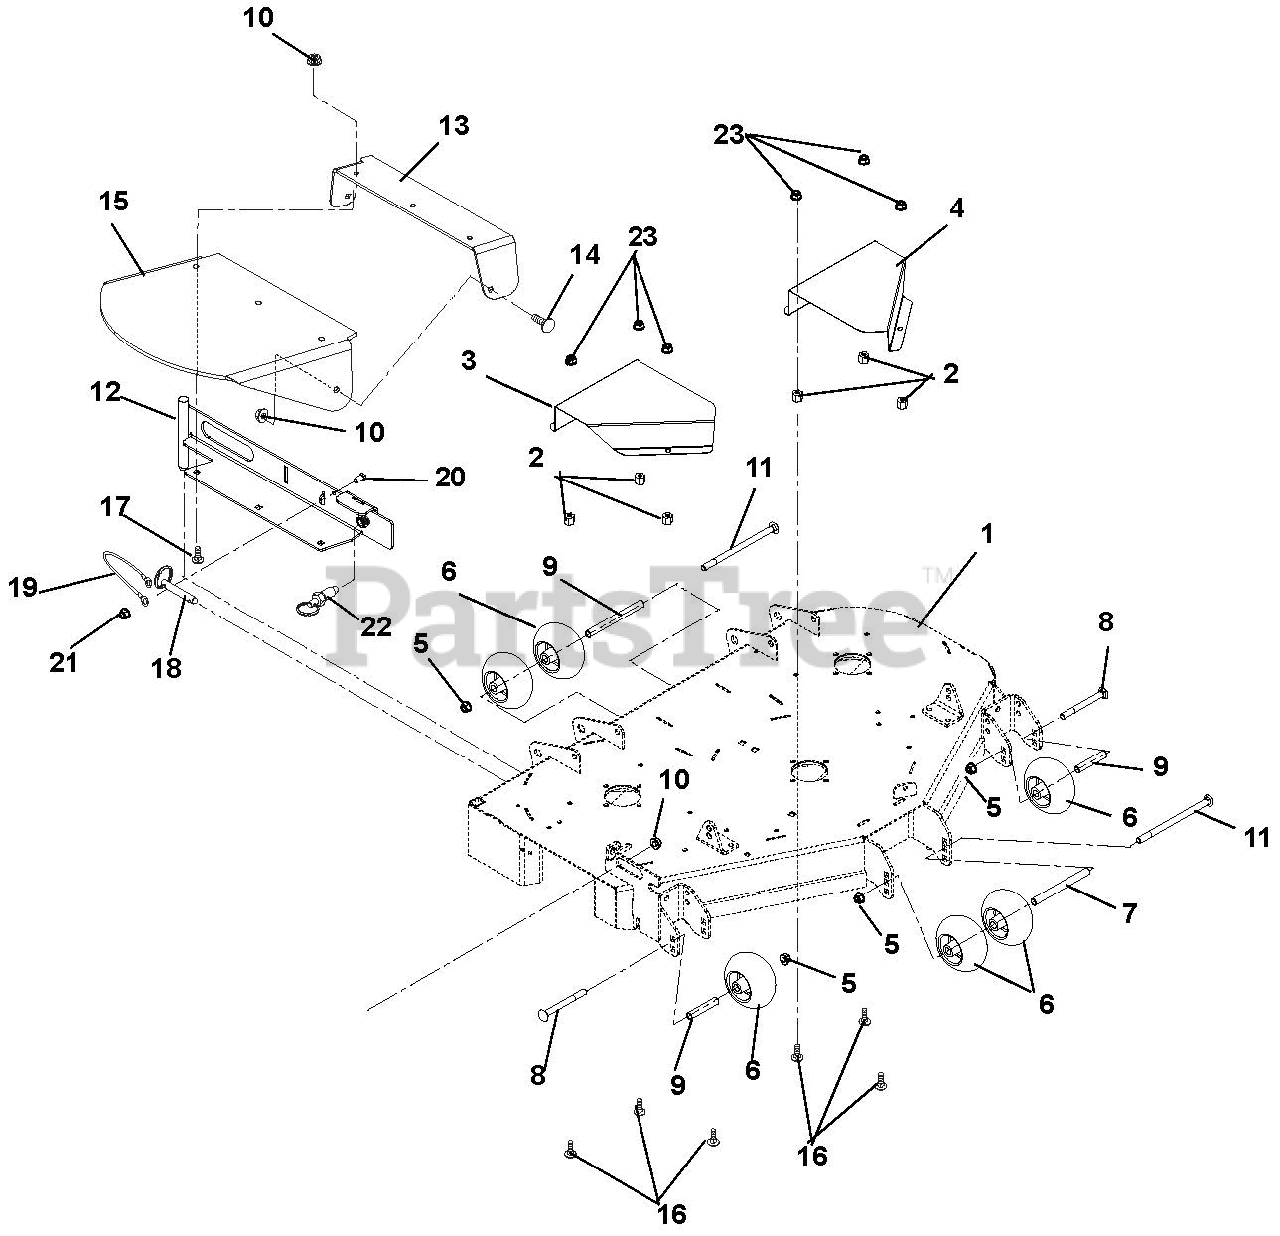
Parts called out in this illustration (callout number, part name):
1	44" Side Discharge Deck Weldment
2	Nut, Heavy Hex .38-16
3	Guard, 44-52 RH Spindle Sheave
4	Guard, 44-52 LH Spindle Sheave
5	Nut .50-13 Nyloc Flange
6	Anti-Scalp Wheel
8	Bolt, Round Head Square Neck .50-13 x 5.00
9	Spacer, .510 x .625 x 3.35
10	Nut, .38-16 Nyloc Flange
11	Bolt, Round Head Square Neck .50-13 x 8.50
12	Weldment, Discharge Chute Support
13	Rubber Discharge Chute Support
14	Bolt, Round Head Square Neck .38-16 x 1.00 Grade 5
15	Chute, Rubber Discharge
16	Bolt, Hex Head .38-16 x 1.25 Grade 5
17	Bolt, Round Head Square Neck .38-16 x 1.25 Grade 5
18	Pin, Spring Ball .375 x 1.50
19	Cable, 6.0 Lanyard
20	Bolt, Hex .25-20 x .75
21	Nut, Locking Top Flange .25-20
22	Pull Pin
23	Nut, Flange .375-16
